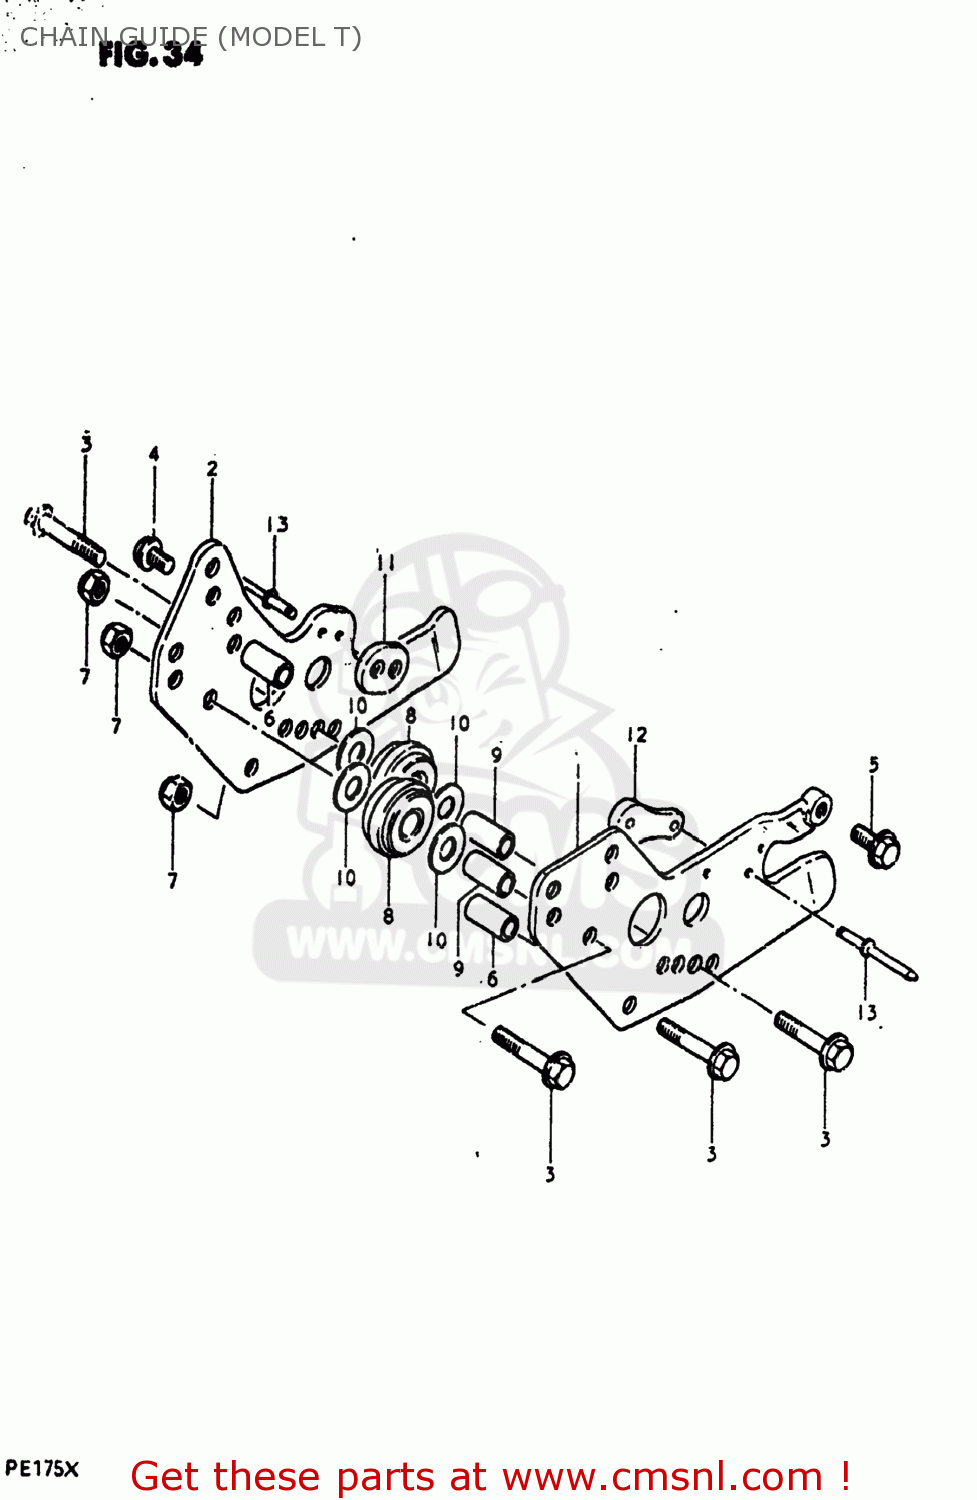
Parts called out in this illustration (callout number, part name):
1	PLATE,CHAIN GUIDE,OUTER
2	PLATE,GUIDE CHAIN
3	BOLT
4	BOLT
5	BOLT
6	SPACER(6.8X10X24.2)
7	NUT
8	ROLLER,CHAIN GUIDE
9	SPACER,CHAIN GUIDE ROLLER
10	WASHER
11	PAD,DRIVE CHAIN GUIDE
12	PAD,DRIVE CHAIN GUIDE
13	RIVET
